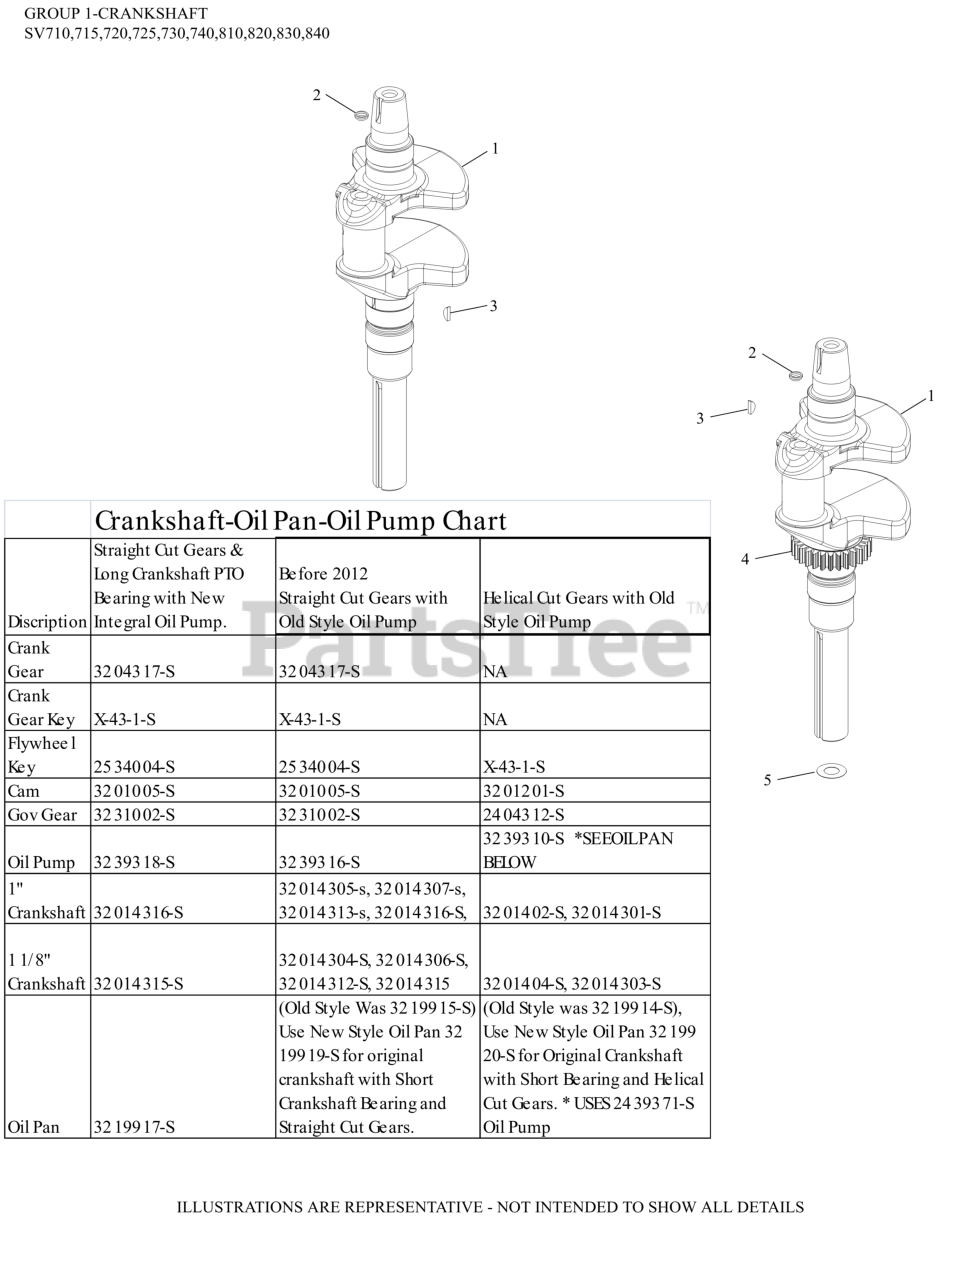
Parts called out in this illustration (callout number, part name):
1	CRANKSHAFT ASSY-USE 32 014 327-S
2	PLUG, CUP
3	KEY, 1/8" X 1/2"
4	GEAR, CRANKSHAFT
5	SPACER (.010")
